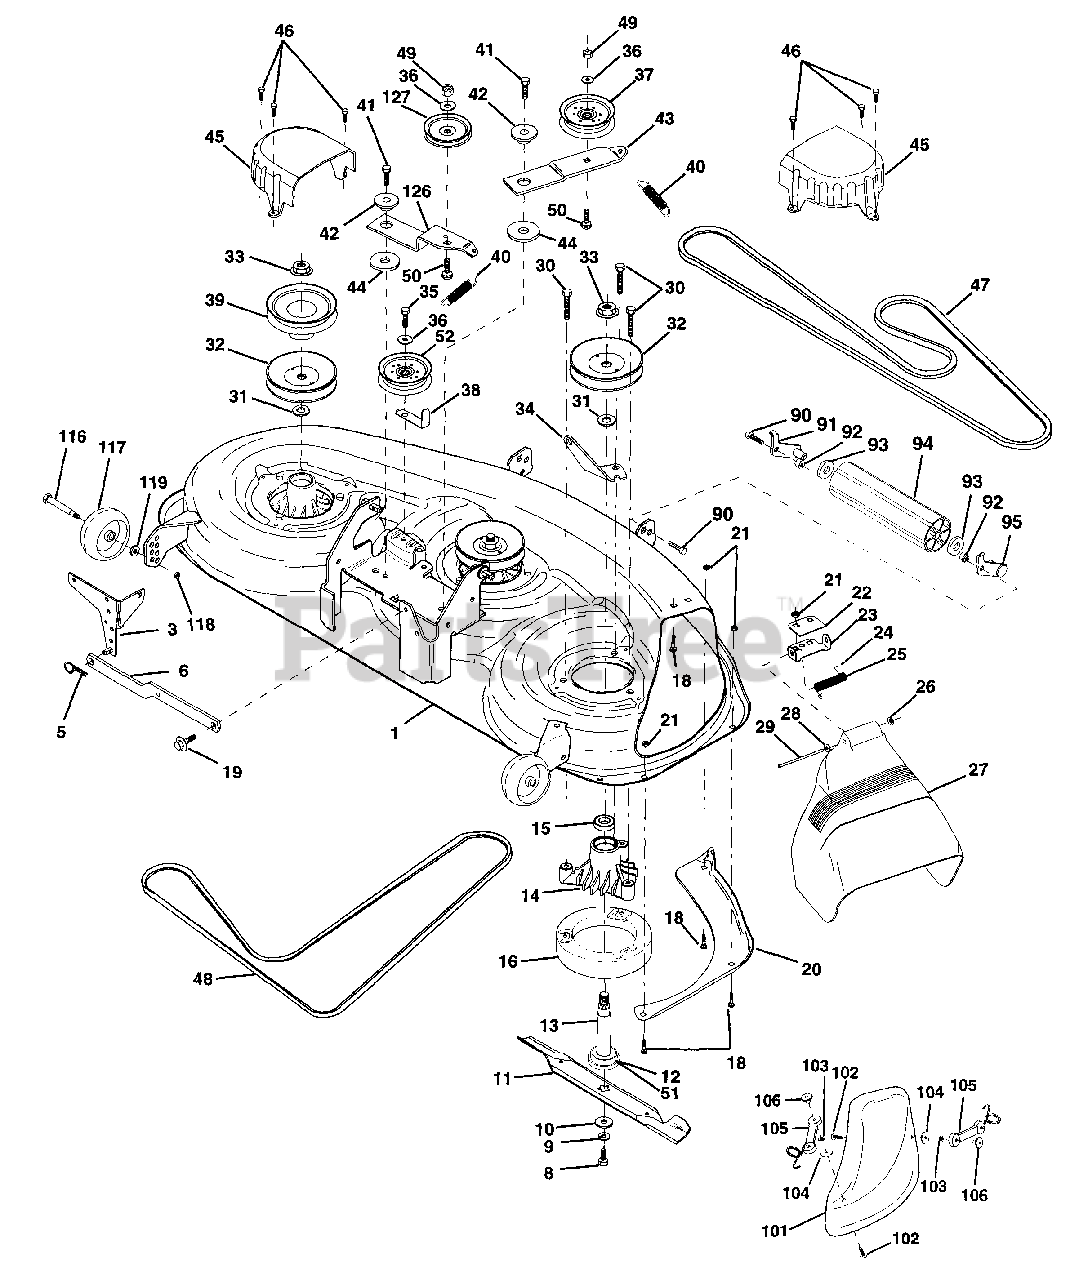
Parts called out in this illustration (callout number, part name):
1	Deck Asm., Mower 46"
3	Bracket Asm., Sway Bar
5	Retainer Spring
6	Arm, Suspension, Rear (Sway Bar)
8	Bolt, Patched 3/8-24 x 1-1/4 Gr. 8
9	Washer, Lock Hvy., Unplated 3/8
10	Washer, Hard Blade, Mower Vented
11	Blade, 46" Mulching
12	Bearing, Ball, Mandrel #6204
13	Shaft Asm. w/Lower Bearing
14	Housing, Mandrel
15	Bearing, Ball, Mandrel
16	Stripper, Mower Round
18	Bolt, Carriage 5/16-18 x 5/8
19	Bolt, Hex Head, Shoulder 5/16-18
20	Baffle, Vortex Mower 46"
21	Nut, Crownlock 5/16-18 UNC
22	Stiffiner, Bracket
23	Bracket, Deflector
24	Cap, Sleeve
25	Spring, Torsion, Deflector
27	Shield, Deflector Mower
28	Washer 11/32 x 5/8 x 16 Ga.
29	Rod, Hinge
30	Screw, Hex Head, Thdroll
31	Washer, Spacer Mower Vented
32	Pulley, Mandrel
33	Nut, Flg. Top Lock Cntr. 9/16
34	Anchor, Spring Deck 46"
35	Screw, Thdroll 3/8-16 x 1-3/4 Tytt
36	Washer 13/32 x 13/16 x 16 Ga.
37	Pulley, Idler, Flat
38	Keeper, Belt, Idler
39	Pulley, Idler, Driven
40	Spring, Secondary 44/46/50 Vent
41	Screw, Thdroll 3/8-16 x 1-1/4 Tytt
42	Spacer, Retainer
43	Arm, Idler Secondary
44	Washer, Hardened
45	Cover, Mandrel Deck
46	Screw, Thdroll. 1/4-20 x 5/8
47	V-Belt, Mower, Secondary
48	V-Belt, Mower, Primary
49	Nut, Crownlock 3/8-16 UNC
50	Bolt, Carriage 3/8-16 x 1-1/2 Gr. 5
51	Washer Felt
52	Pulley Idler Flat 46 PRI drive
90	Bolt Fin Hex 3/8-16 x 1
91	Bracket Asm Noseroller LH
92	Nut Lock Hex W/Ins 3/8-16 UNC
93	Washer 17/32 x 7/8 x 16 Ga.
94	Roller Nose
95	Bracket Asm Noseroller RH
101	Cover, Mulching
102	Screw
103	Washer, Lock #10
105	Latch Asm. Bagger
106	Nut, Weld
116	Bolt, Shoulder
117	Gauge Wheel, Wide
118	Nut, Centerlock 3/8-16 UNC
119	Washer 3/8 x 7/8 x 14 Ga.
126	Arm, Idler, Primary Deck 46"
127	Pulley, Idler, V-Groove Dim. 4.25
